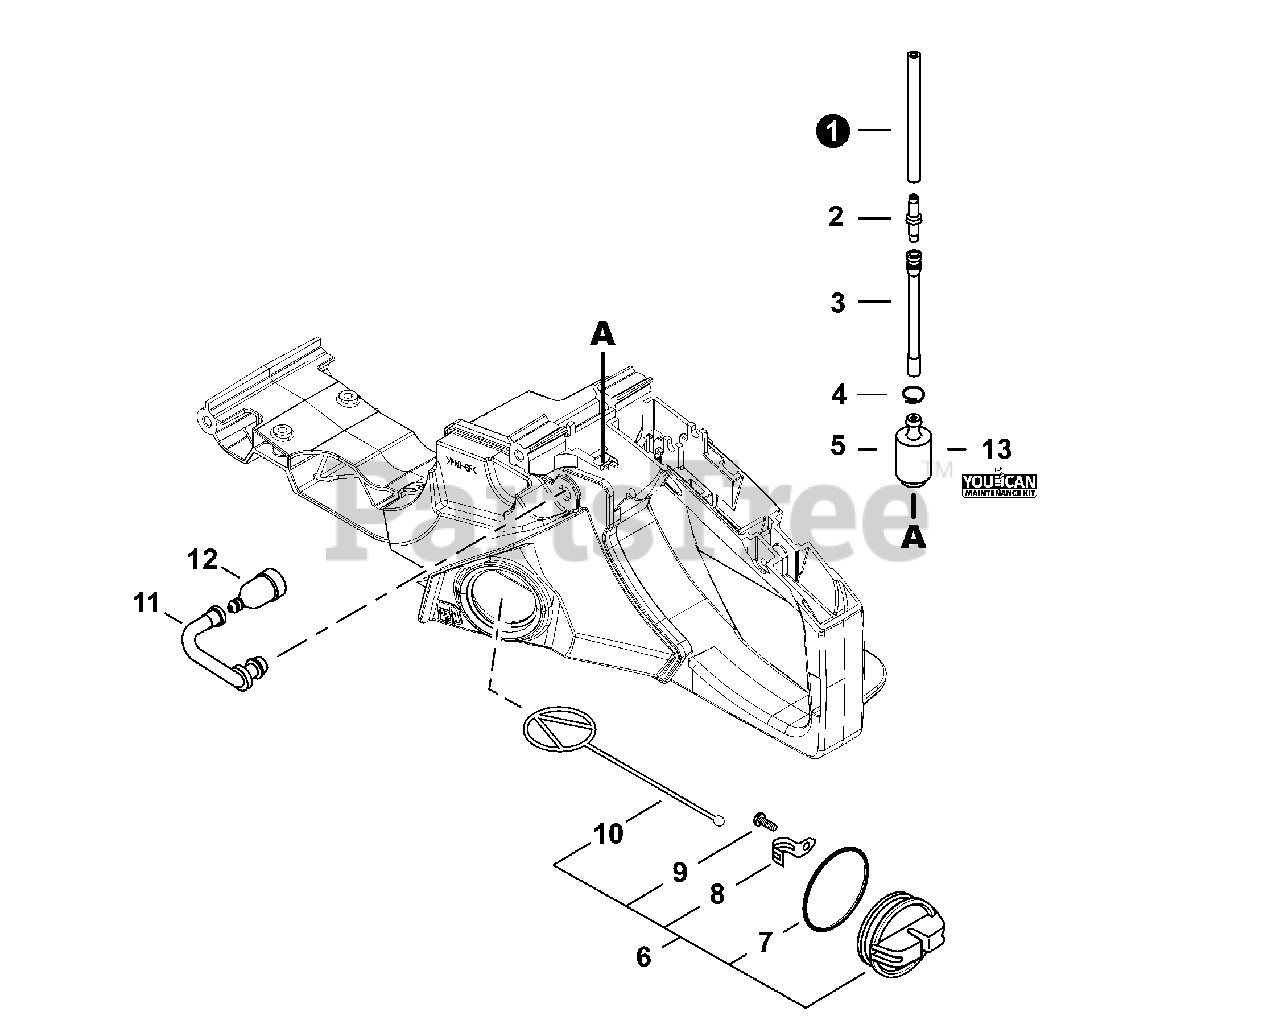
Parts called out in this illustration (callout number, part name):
1	PIPE, FUEL 3×6×75
2	CONNECTOR, PIPE
3	PIPE, FUEL
5	FILTER, FUEL
6	CAP ASSY, FUEL
7	O-RING 29
8	RETAINER, CONNECTOR
9	SCREW, TAPPING 3×8
10	CONNECTOR, CAP L= 60 MM
11	PIPE, FUEL VENT
12	VENT ASSY
13	TUNE-UP KIT - YOUCAN™
